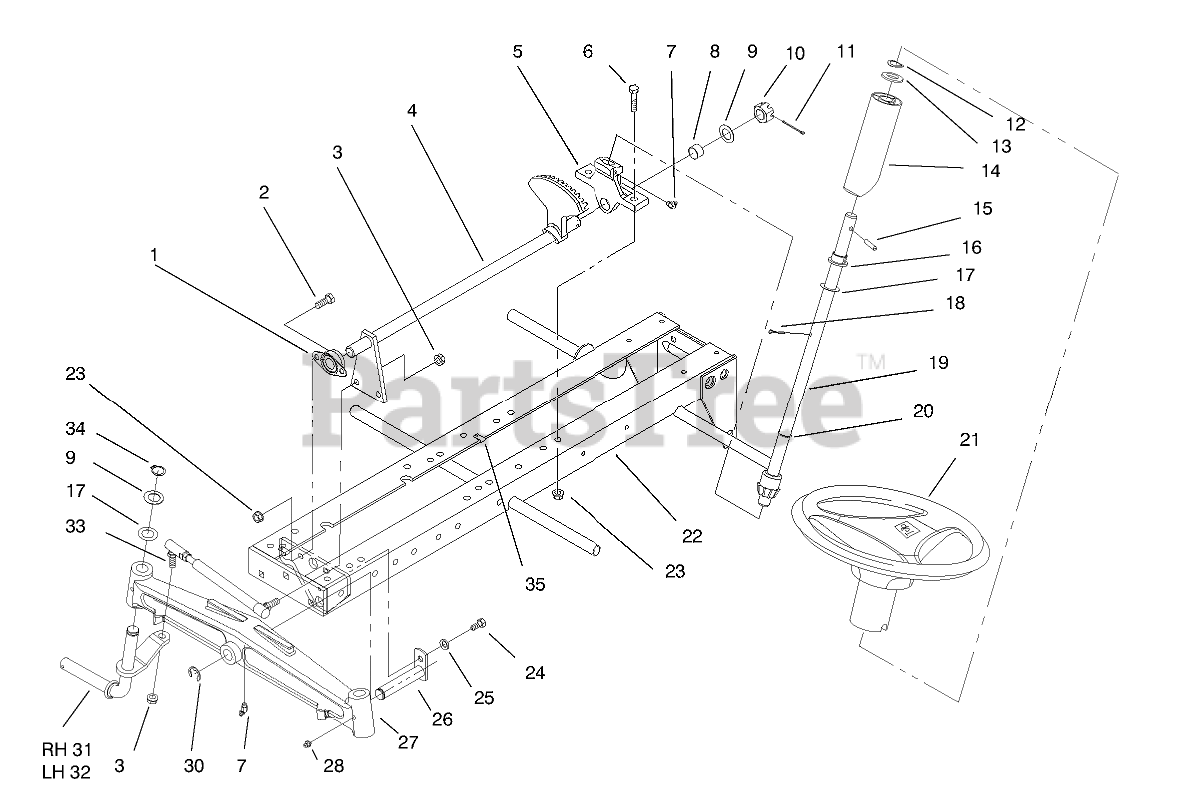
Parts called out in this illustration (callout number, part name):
1	BEARING-FLANGED
2	SCREW-HH
3	NUT-LOCK
4	Shaft-Steering
5	Support-Lower Steering
6	SCREW-HH
7	FITTING-LUBE, 45 DEG
8	BEARING-BRONZE
9	WASHER
10	NUT-HEX, SLOTTED
11	PIN-COTTER
12	WASHER-BOWED
13	WASHER-FLAT
14	TUBE-STEERING
15	PIN-ROLL
16	BEARING-FLANGED
17	WASHER-SHIM
18	PIN-COTTER
19	STEERING SHAFT ASM
20	O-RING
21	WHEEL - STEERING 15"
21:1	COVER-WHEEL
22	FRAME ASM
23	NUT-LOCK, NI
24	SCREW-HH
25	WASHER-LOCK
26	PIN AND PLATE ASM
27	AXLE-FRONT
28	FITTING-GREASE
30	E-RING
31	SPINDLE ASM-RH
32	SPINDLE ASM-LH
33	ASM-Rod
34	RING-RETAINING
35	CLIP-WIRE
